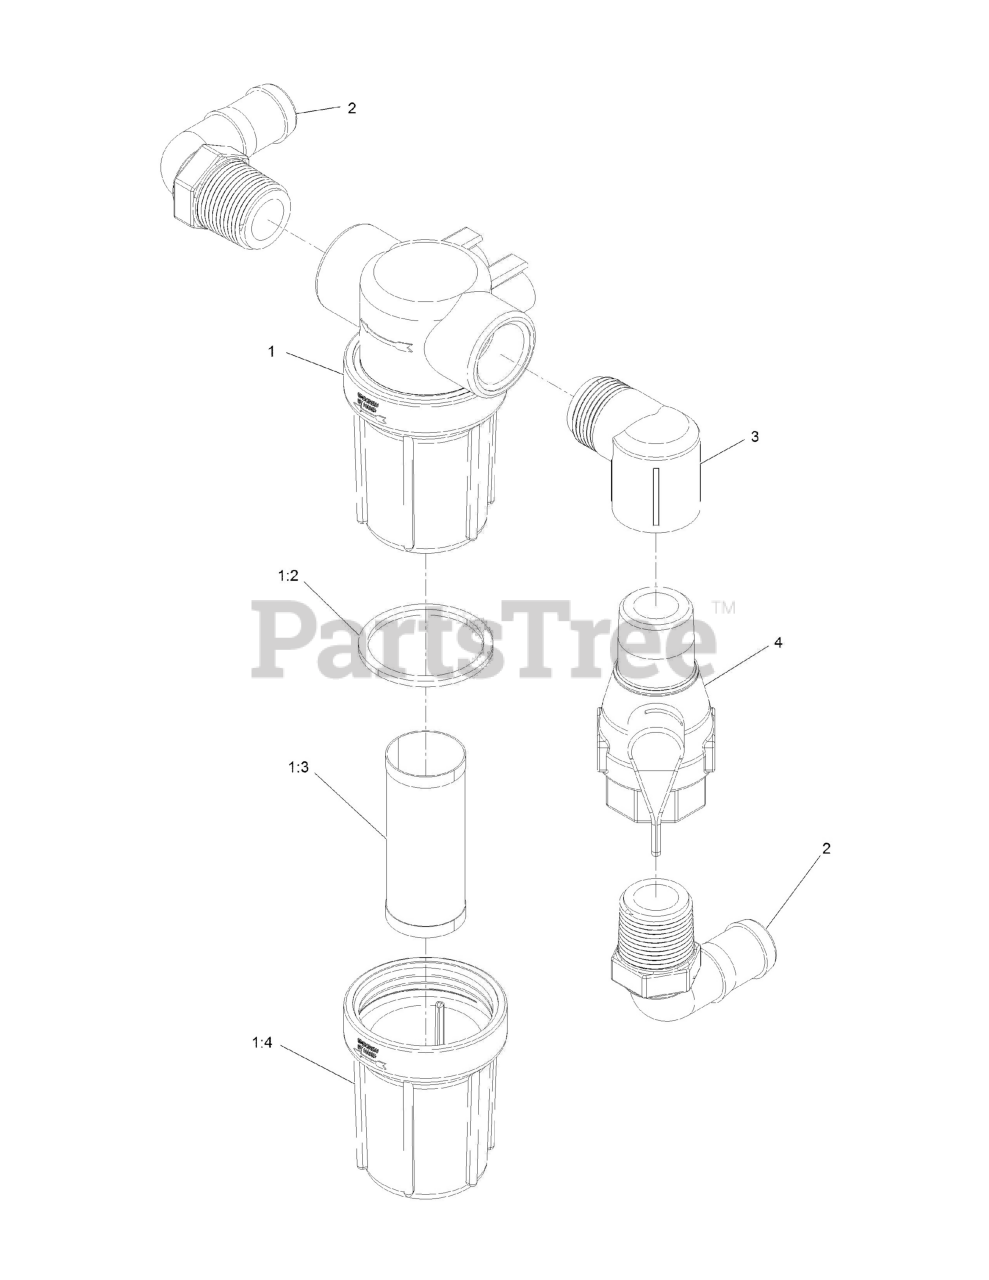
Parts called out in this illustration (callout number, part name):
1	STRAINER-LINE
1:2	GASKET-HEAD, LINE STRAINE
1:3	SCREEN-STRAINER, 30 MESH
1:4	BOWL-STRAINER
2	ELBOW-HOSEBARB
4	VALVE-BALL
